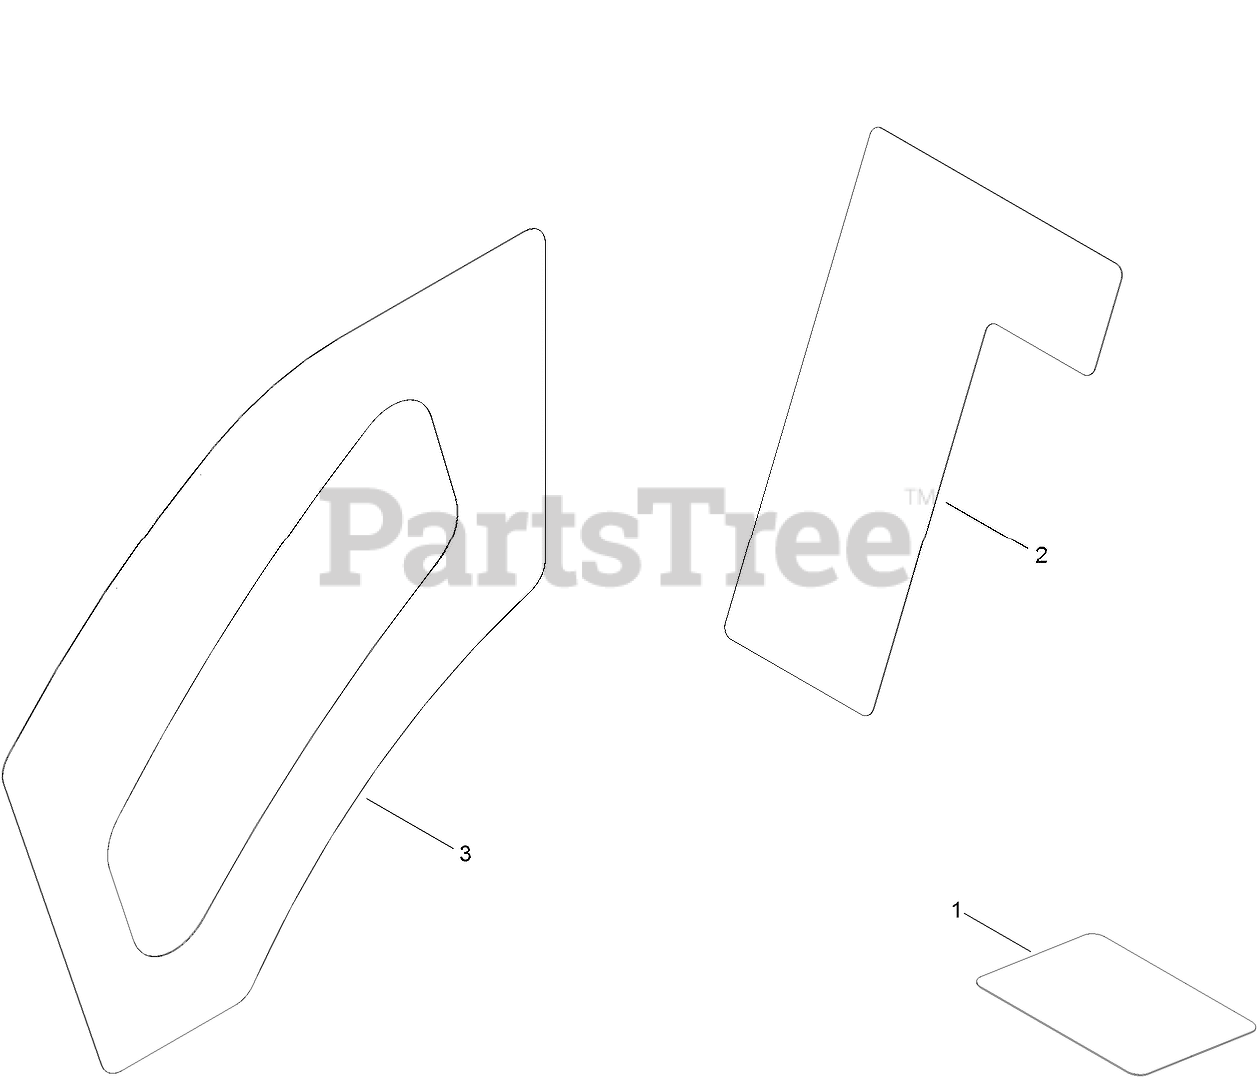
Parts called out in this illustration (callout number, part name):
1	DECAL-MAINTENANCE
2	DECAL-SMART SPEED
3	DECAL-HOC
